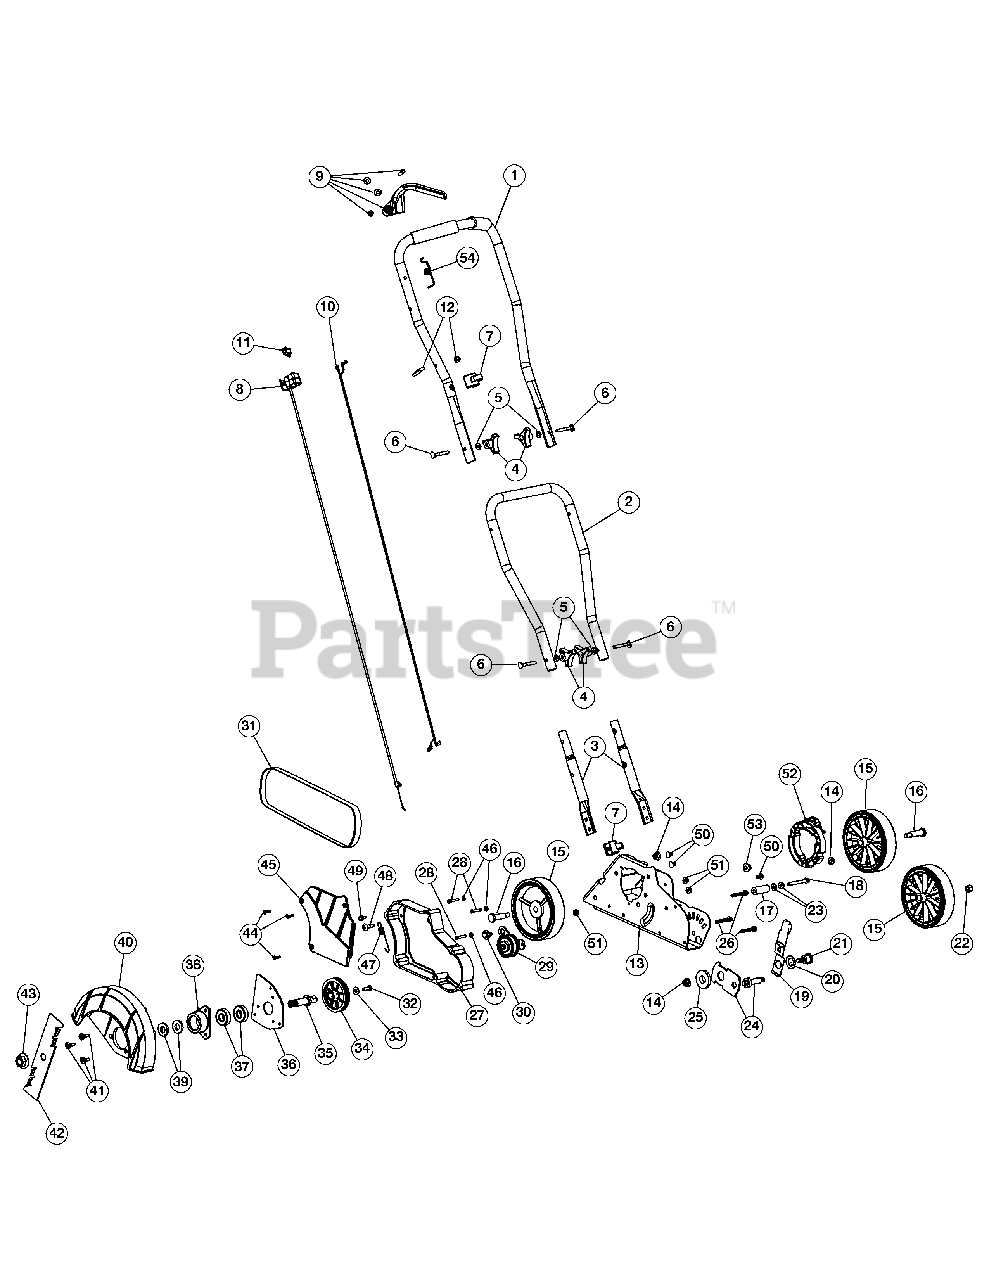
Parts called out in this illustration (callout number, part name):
1	Upper Handle
2	Middle Handle
3	Handle Extension
4	Handle Knob
5	Washer
7	Cable Guide
8	Throttle Cable
9	Throttle Lever w/Hardware
10	Lead Wire
11	On/Off Switch
12	Starter Rope Guide
13	Edger Frame
16	Wheel Bolt
18	Spacer Screw
19	Height Adjustment Lever Assembly
21	Shoulder Screw
25	Height Adjustment Spacer
26	Spindle Plate Screw
27	Spindle Spacer
29	Idler Pulley Assembly
30	Shoulder Screw
34	Pulley
35	Blade Spindle
36	Spindle Plate
38	Bearing Cup
39	Washer
40	Blade Guard
41	Screw
45	Belt Cover
50	Bolt
